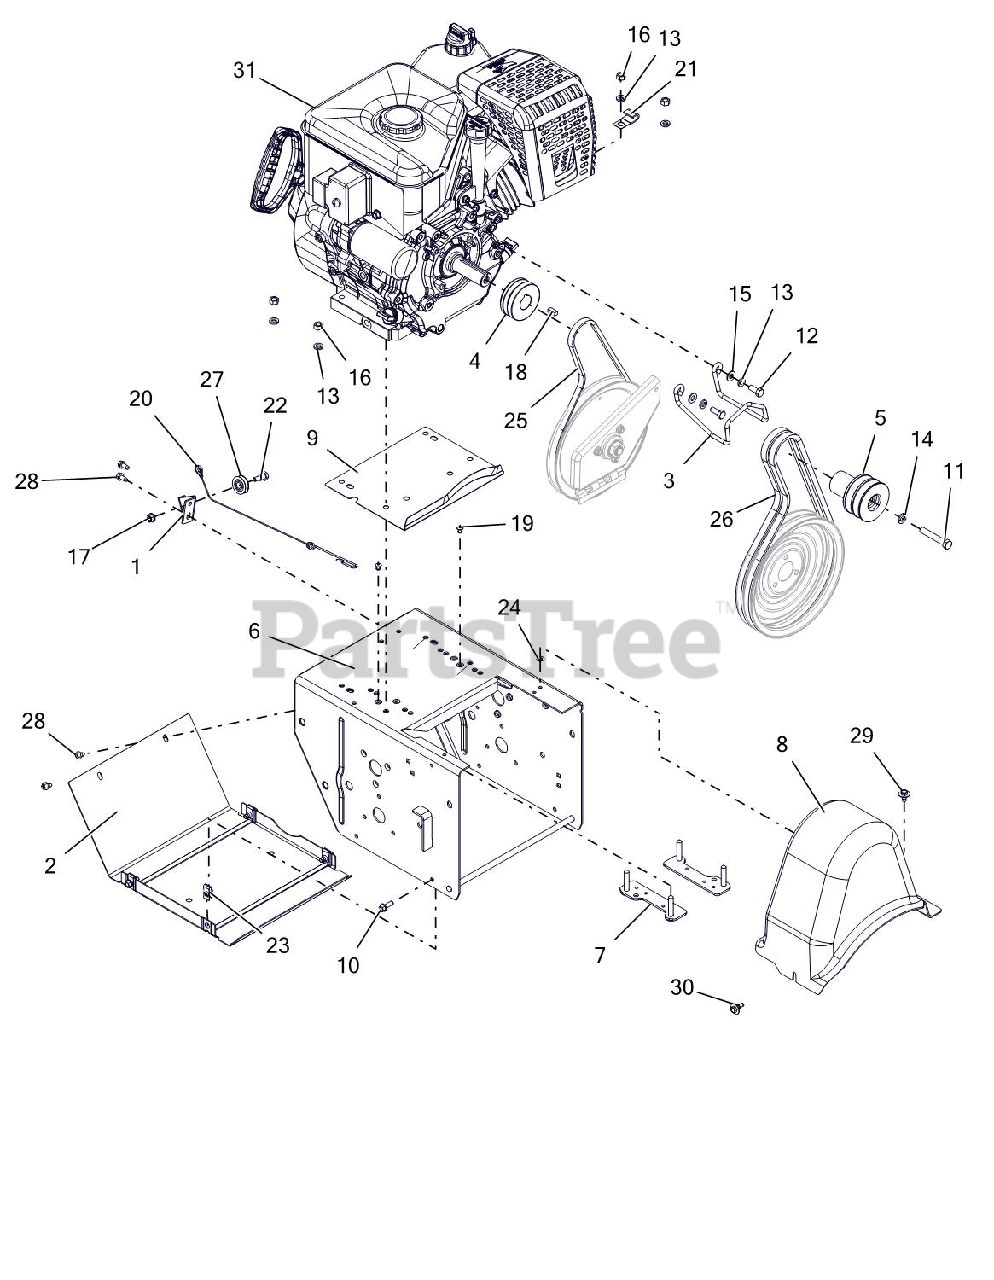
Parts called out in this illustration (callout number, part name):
1	BRACKET, CABLE PULLEY
2	COVER, BOTTOM
3	FINGER, BELT
4	SHEAVE, DRIVE
5	SHEAVE, ATTACHMENT 2-GRV
6	FRAME, MAIN-DELUXE(WELDMENT)
7	STRAP, BOLT-LARGE
8	COVER, BELT-LARGE
9	BAFFLE, WATER - LARGE BLOCK
10	BLT-HEX .25-20X.75 HWH YZ GR5
11	BLT-HEX .38-24X2.25 YWZC GR5
12	BLT-HEX .31-24X.75 YWZC GR5
13	WSHR-LK .312X.097 HVY YWZC
14	@WSHR-LK .38X.094 REG YWZC
15	@WSHR-FL-STL.344X.688X.065YWZC
16	@NUT-HEX .31-18 YWZC
17	@NUT-LK-TOP-FLG .25-20 YWZC
18	KEY-SQ .25X.625X.25 SAE 8630
19	RVT-POP .187 YZ
20	CABLE, LOWER TRACTION,SS & PRO
21	J-CLAMP
22	BOLT, SHLDR-.375X.375X.25-20
23	NUT-RTNR .25-20X.56
24	NUT-PUSH .25X.50 O.D.
25	V-BELT, 3L-WRAPPED
26	V-BELT, HA-RAW EDGE (SET)
27	PULLEY, CABLE
28	SCR-TAP .25-20X.50 HWH TR YWZ
29	SCR-TAP .25-20X.50 LGHWH TR YZ
30	SCR-TAP .25-20X.5 CAPTIVE
31	ENGINE, AX369 GEN 3 240V/60W
